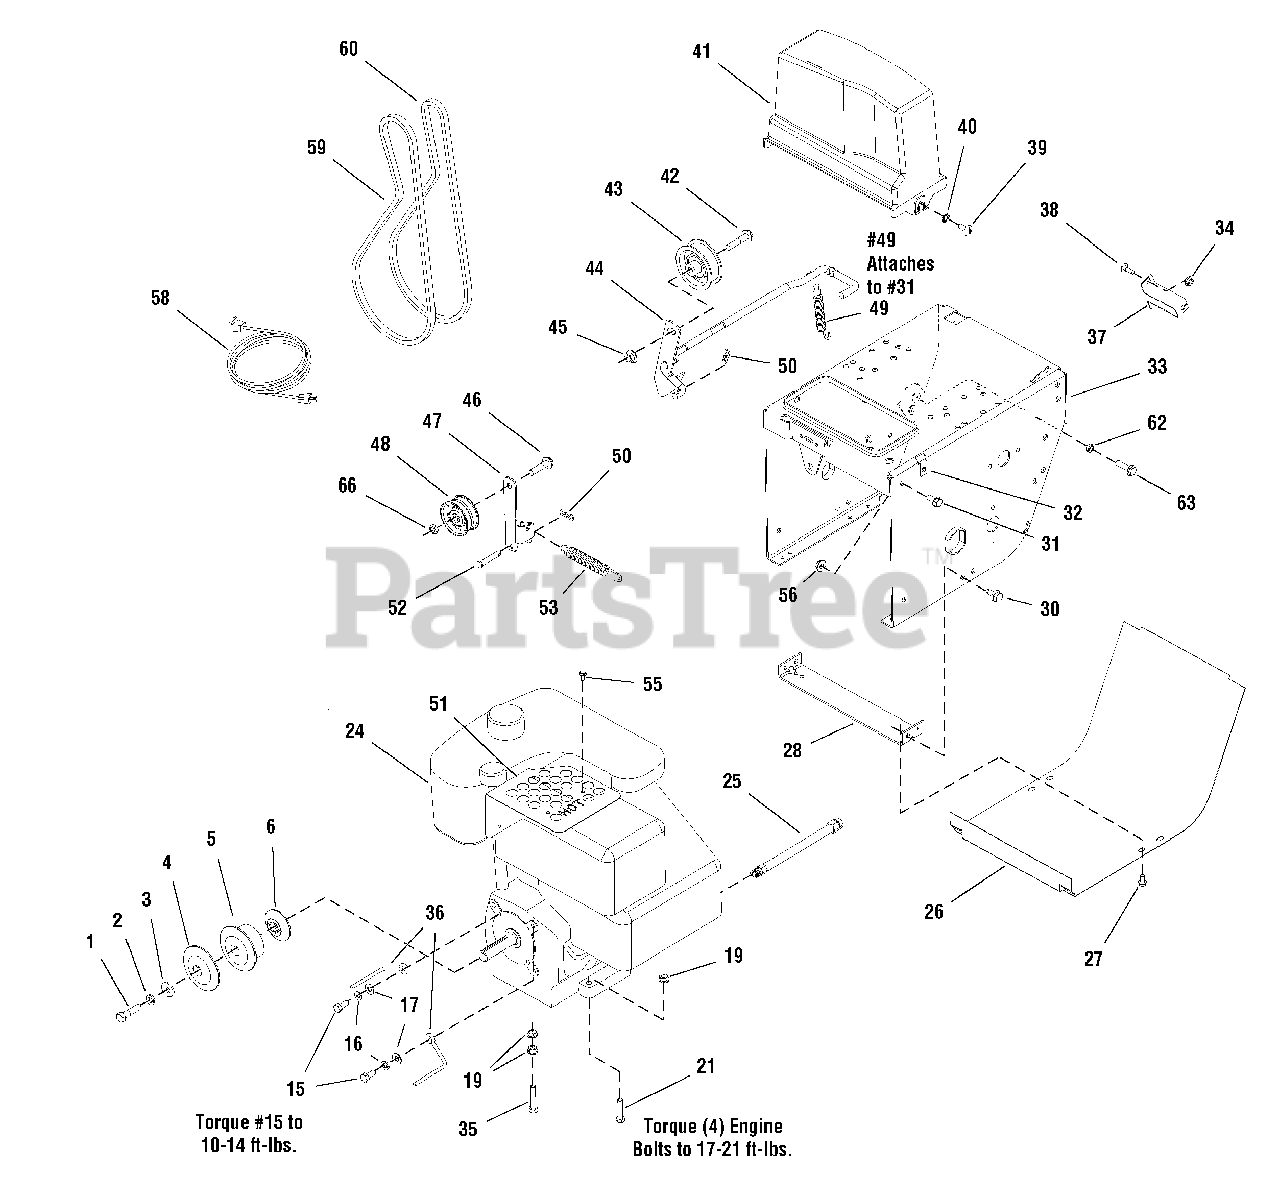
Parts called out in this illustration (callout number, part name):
1	CAPSCREW, Hex Head 3/8-24 x 1-1/2, G8
2	LOCKWASHER, Spring 3/8
3	WASHER, 3/8, .41 ID x 1 OD x .13 THK
4	PULLEY, Engine Outside
5	PULLEY, Engine Middle
6	PULLEY, Engine Inside
15	CAPSCREW, Hex Head 5/16-24 x 3/4, G5
16	LOCKWASHER, Spring 5/16
17	WASHER, 5/16, 0.34 ID x 3/4 OD x .06 THK
19	NUT, Hex Whiz Lock Flange 5/16-18
21	CAPSCREW, Hex Head, 5/16-18 x 1-1/2, G5
25	HOSE, Oil Drain
26	COVER, Bottom Frame
27	SCREW, Hex Washer Head Taptite, 1/4-20 x 1/2
28	SUPPORT, Tie Bar
30	SCREW, Hex Washer Head Taptite, 5/16-18 x 3/4
31	SCREW, Hex Whiz Lock Flange, 5/16-18 x 3/4
32	NUT, Speed, Lug Type, 5/16-18
33	FRAME ASSEMBLY
34	NUT, Hex Keps, 1/4-20 Conical Washer
35	CAPSCREW, Hex Head, 5/16-18 x 1-3/4, G5
36	STOP, Belt
37	SUPPORT, Clutch Cable L.F.
38	CARRIAGE BOLT, 1/4-20 x 3/4, G5
39	SCREW, Truss Head Slotted, 5/16-18 x 3/4
40	LOCKWASHER, External Tooth 5/16
41	COVER, Belt
42	SCREW, Hex Whiz Lock Flange, 3/8-16 x 1-3/4
43	PULLEY, Idler, 2-3/4
44	ROD & ARM ASSEMBLY, Clutch/Brake
45	NUT, Hex Whiz Lock Flange, 3/8-16
46	SCREW, Hex Head, 3/8-16 x 1-1/2 x .141
47	ARM, Idler, 5-3/4
48	PULLEY, Idler
49	SPRING, Extension
50	PIN, Quick
51	GUARD, Muffler
52	PIN, Flat Head Drilled
53	SPRING, Extension L.F.
55	SCREW, Hex Taptite, 10-24 x 1/2
56	NUT, Hex Whiz Lock Flange, 5/16-18
58	CORD, Electric Extension
59	V-BELT, 3L 31.00 (Drive)
60	V-BELT, HA 41.3 (Auger)
62	NUT, Hex, 5/16-18
63	CAPSCREW, Hex-head, 5/16-18 X 1
66	NUT, Hex Toplock Jam, 3/8-16
